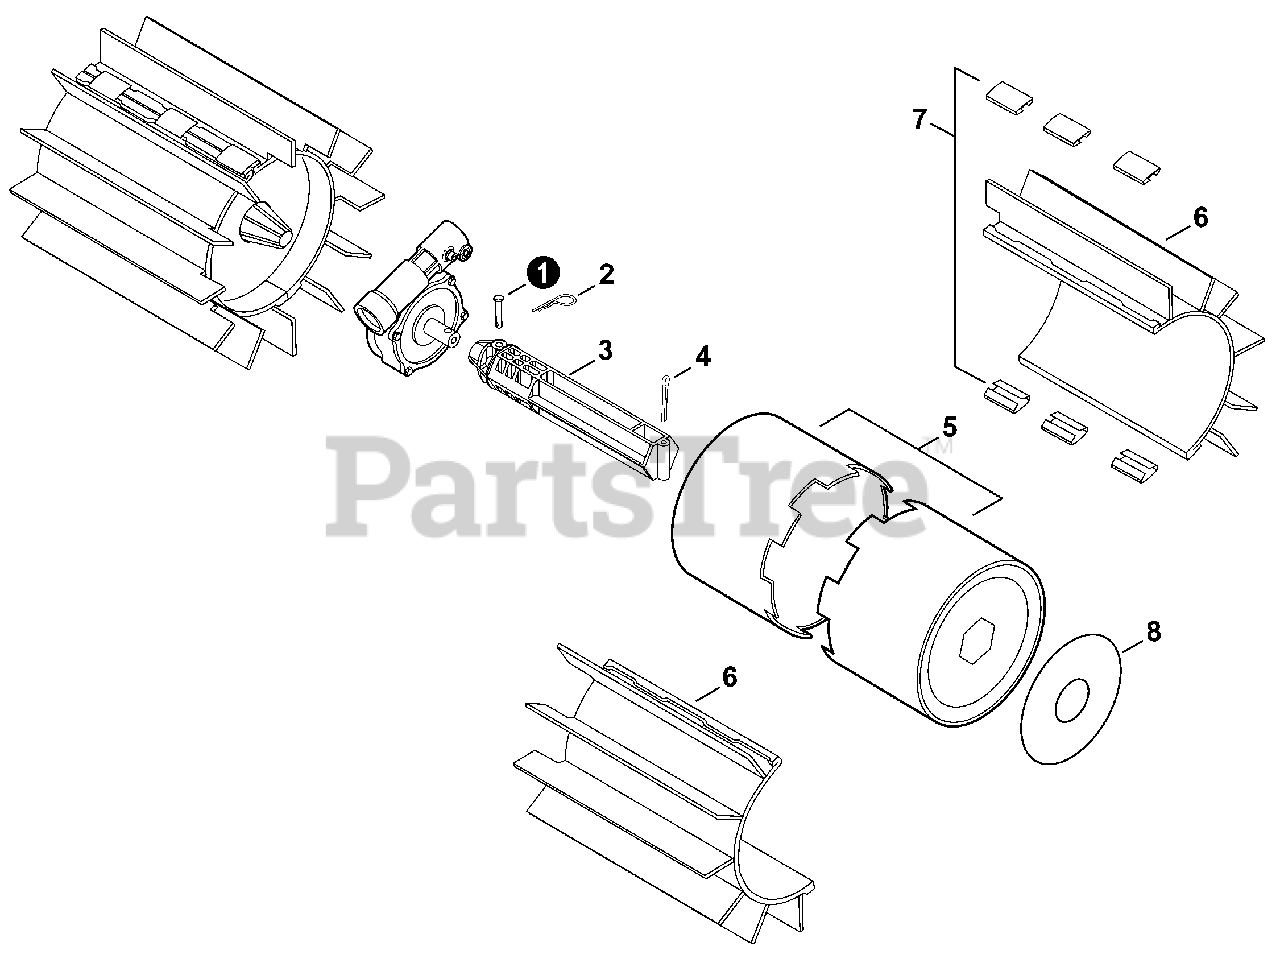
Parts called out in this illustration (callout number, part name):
1	PIN, CLEVIS
2	PIN, HITCH
3	AXLE, DRUM
4	PIN, COTTER
5	HUB, DRUM
6	BELT, SWEEPER
7	CLIP, BELT
8	LABEL, PROPADDLET
